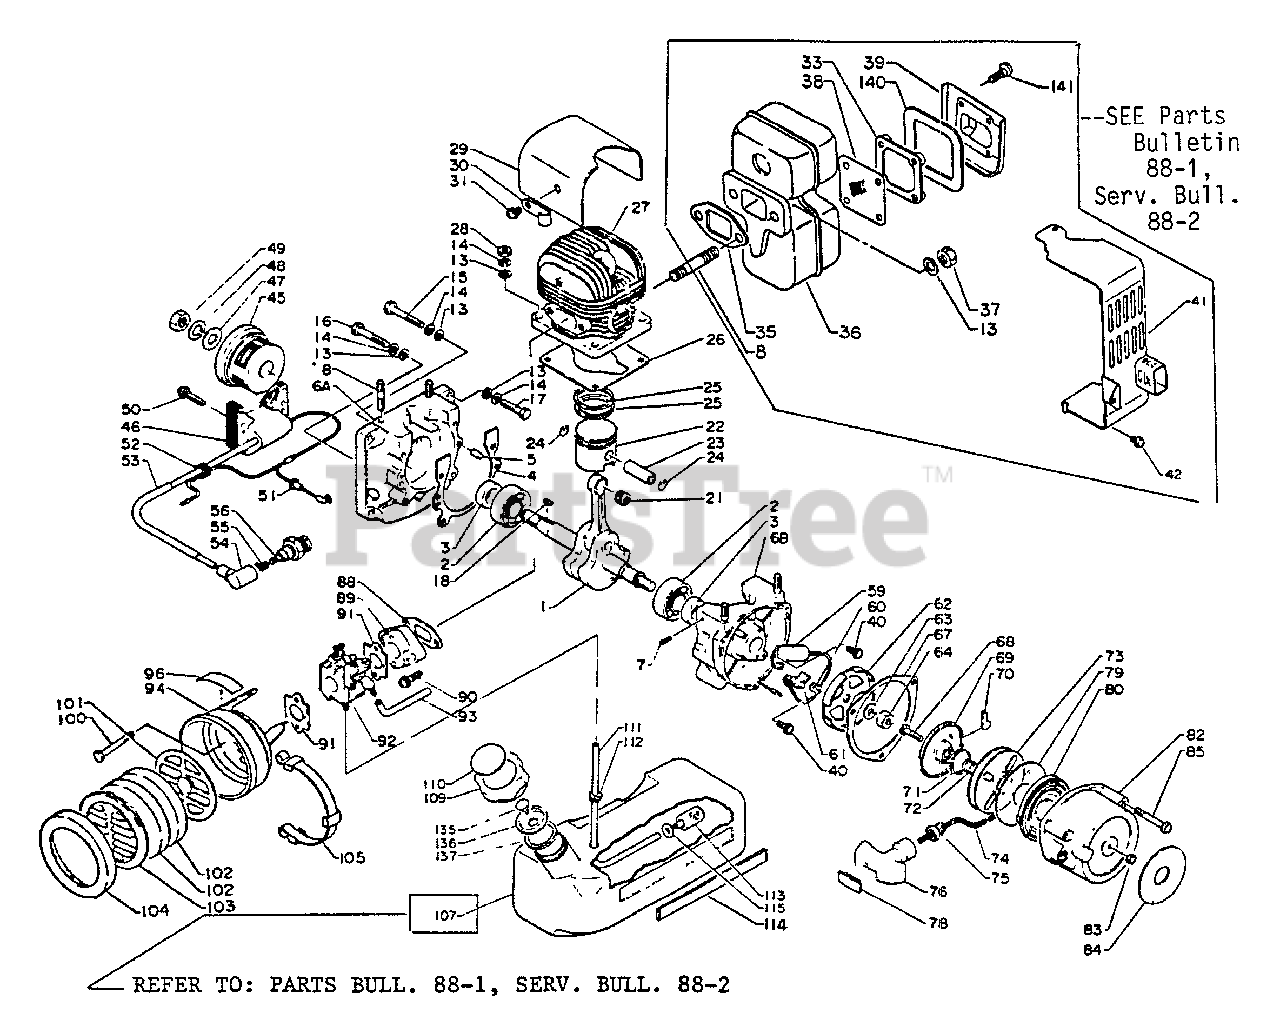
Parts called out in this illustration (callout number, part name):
1	CRANKSHAFT ASSY
2	BEARING, BALL - 6202
3	SEAL, OIL
4	GASKET, CRANKCASE
5	PIN - LOCATING
6	CRANKCASE KIT
6A	CRANKCASE KIT
6B	CRANKCASE KIT
7	CONNECTOR
13	WASHER - 6
14	LOCKWASHER - 6
15	BOLT
16	BOLT
17	BOLT - 6X25
21	BEARING, NEEDLE
22	PISTON
23	PIN, PISTON
24	RING, RETAINING - 8
25	RING, PISTON
26	GASKET, CYLINDER
27	CYLINDER
28	LOCKNUT - 6
29	SHIELD, CYLINDER
31	BOLT - 6X10
33	RETAINER, SCREEN
35	GASKET, EXHAUST
37	LOCKNUT - 6
38	SCREEN, SPARK ARRESTOR
39	GUIDE, EXHAUST
40	SCREW - 4X10
41	COVER, EXHAUST
42	SCREW - 5X14
45	FLYWHEEL
46	COIL, IGNITION
48	LOCKWASHER
50	SCREW - 5X25
54	CAP, SPARK PLUG
55	TERMINAL, SPARK PLUG CAP
56	SPARK PLUG -- BM-6A
59	CONDENSER
61	CONTACT POINT SET
62	CATCHER, PAWL
63	WASHER, CLUTCH
67	GASKET, STARTER
69	PLATE, FRICTION
70	PAWL, STARTER
71	SPRING, RETURN
72	SPRING
73	REEL, ROPE
74	ROPE, STARTER - 4X880
75	GUIDE, ROPE
76	GRIP, STARTER
79	PLATE, STARTER
80	SPRING, REWIND
82	CASE, STARTER
83	NUT - 5 -- CAP
84	LABEL - ECHO
85	SCREW - 5X40
88	GASKET, INTAKE
89	INSULATOR, INTAKE
90	SCREW - 6X25
91	GASKET, INTAKE
92	CARBURETOR WA-55
93	PIPE - IMPULSE
94	CASE, AIR FILTER
96	LABEL - CHOKE
100	BOLT
101	RETAINER, AIR FILTER
102	FILTER, AIR
103	COVER, AIR FILTER
104	COVER, AIR FILTER
107	TANK, FUEL
109	CAP
110	LABEL - FUEL MIX
111	PIPE, FUEL - SPIRAL
112	GROMMET
113	FILTER, FUEL
114	LABEL - NAME
115	WASHER - 5
136	HOLDER, VENT
137	GASKET, CAP
140	GASKET, EXHAUST
141	SCREW - 4X14
